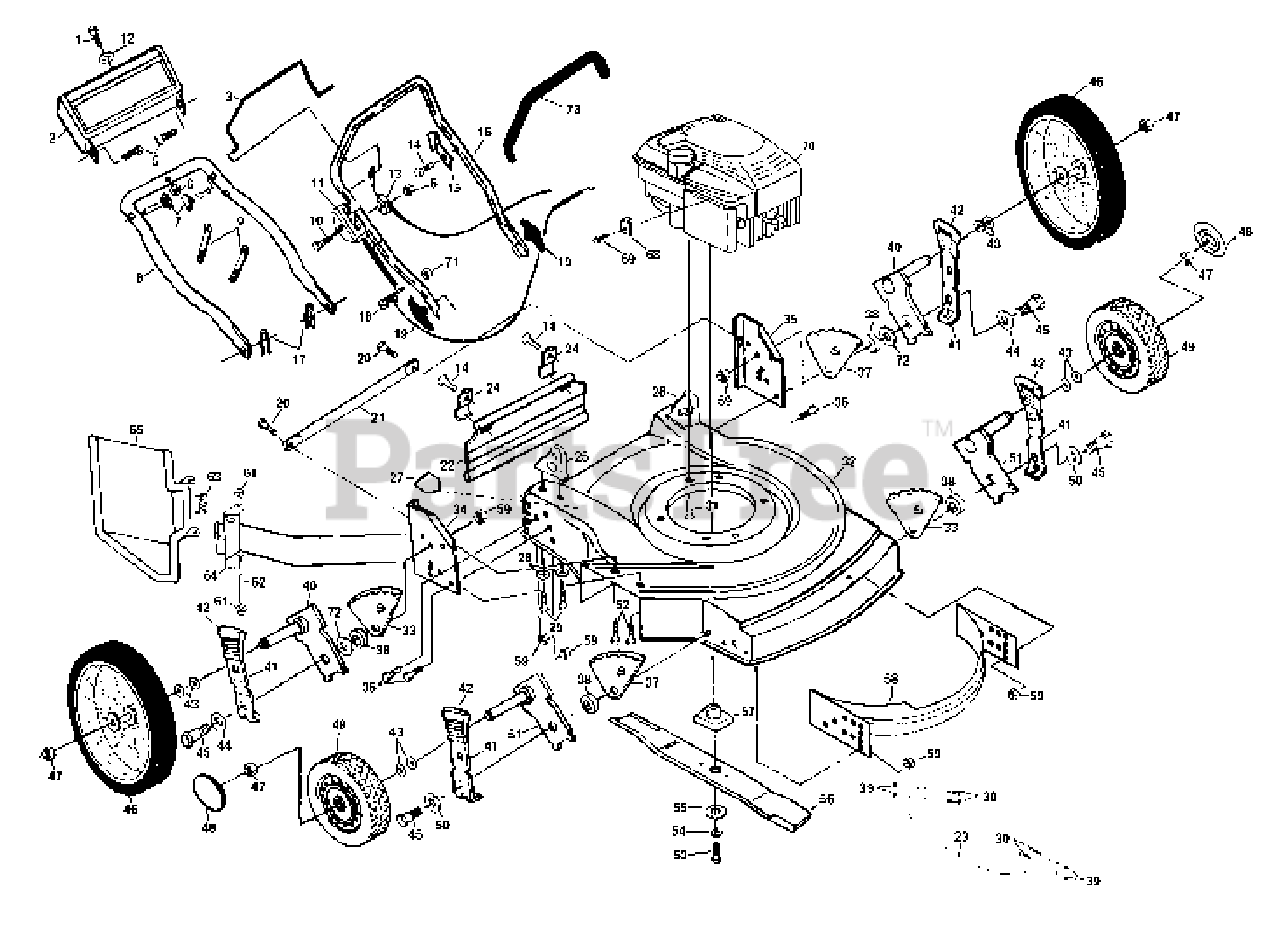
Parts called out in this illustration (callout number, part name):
1	Hex Head Washer Screw 1/4-20 x 1-1/2
2	Trim Plate
3	Control Bar
5	Self-tapping Screw #10-24 x 5/8
6	Locknut 1/4-20
7	Handle Bolt 5/16-18 x 1-3/4
8	Lower Handle
9	Wire Tie
10	Hex Washer Head Screw 1/4-20 x 2.12
11	Throttle Control
13	Engine Zone Control Cable
14	Hex Washer Head Screw #10-24 x 1/2
15	Up-Stop Bracket
16	Upper Handle
17	Hairpin Cotter
18	Rope Guide
19	Handle Knob
20	Self-tapping Screw 1/4-20 x 1/2
21	Support Rod
22	Rear Skirt
23	Mulching Baffle
24	Skirt Bracket
25	Handle Bracket Assembly (Right)
26	Handle Bracket Assembly (Left)
27	Danger Decal
29	Thread Cutting Screw 5/16-18 x 1-3/4
30	Machine Screw
31	Thread Rolling Screw 3/8-16 x 1
32	Lawn Mower Housing
33	Wheel Adjusting Bracket (LF/RR)
34	Wheel Support Bracket (Right)
35	Wheel Support Bracket (Left)
36	Hex Head Bolt 3/8-16 x 3/4
37	Wheel Adjusting Bracket (RF/LR)
38	Spacer
39	Hex Locknut
40	Axle Arm Assembly (Rear)
41	Selector Spring
42	Selector Knob
43	Washer
44	Washer
45	Shoulder Bolt 3/8-16
46	Wheel & Tire Assembly
47	Locknut
49	Wheel & Tire Assembly
51	Axle Arm Assembly (Front)
52	Hex W/Sems 1/4-20 x 3/8 Screw
53	Hex Head Screw 3/8-24 x 1-3/8 Gr. 8
54	Helical Washer 3/8
55	Hardened Washer
57	Blade Adapter
58	Front Baffle & Rear
59	Locknut 3/8-16
62	Hinge Rod
63	Torsion Spring
64	Housing Bracket Assembly
65	Discharge Guard
68	Cable Clamp
69	Thread Rolling Screw #10-32 x 5/8
71	Locknut, Keps 1/4-20
72	Flat Washer 3/8
73	Handle Grip, Foam
